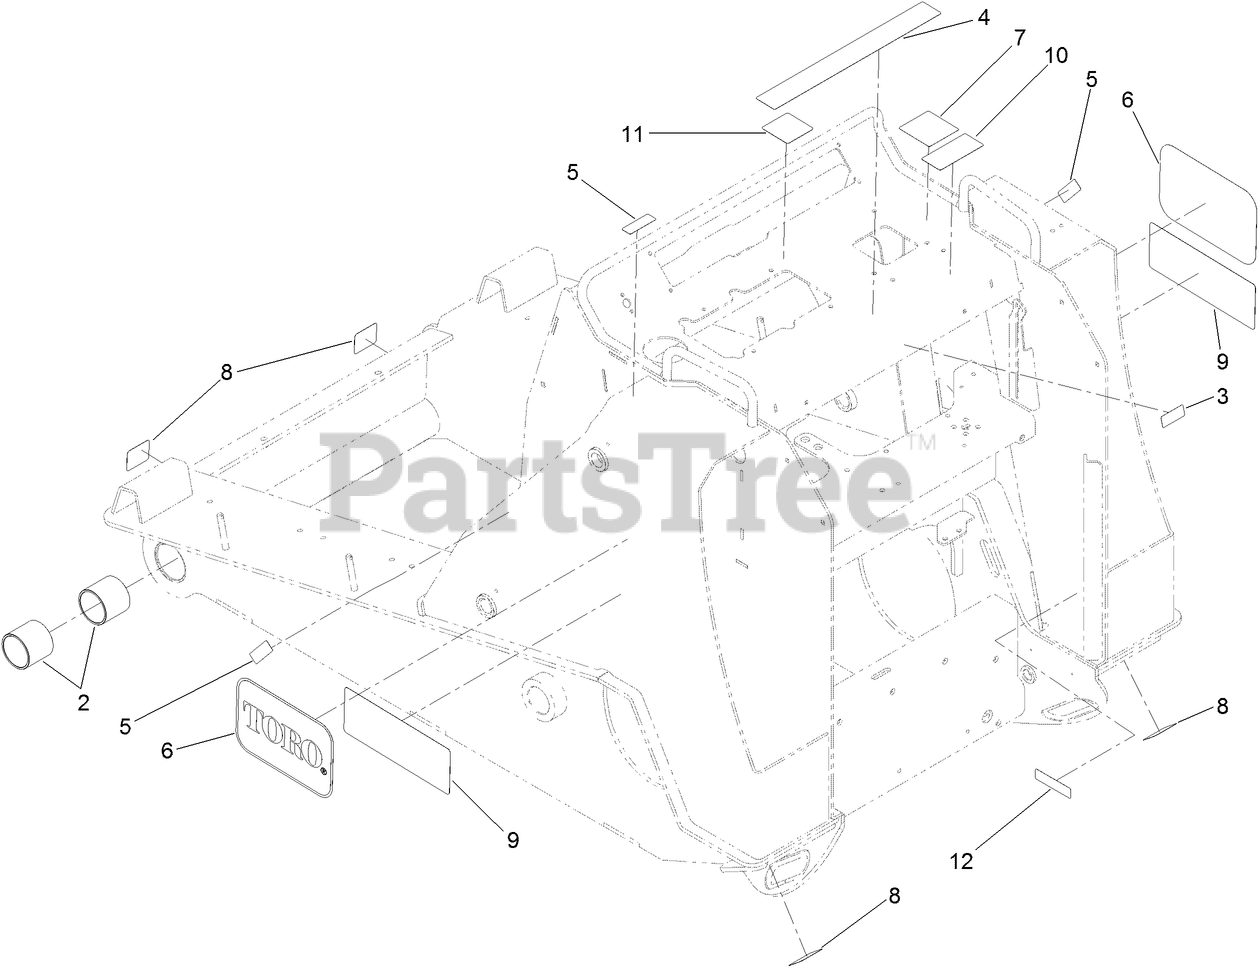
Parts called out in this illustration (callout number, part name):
2	BUSHING-CYL
3	DECAL-SURFACE, HOT
4	DECAL-SAFETY
5	DECAL-WARNING, PINCH POINT
6	DECAL
7	DECAL-CONTROL, LOADER
8	DECAL-TIE DOWN
10	DECAL-EXTENDED ARM SAFETY
11	DECAL-LOADER CONTROLS
12	DECAL-ARRESTOR, SPARK
